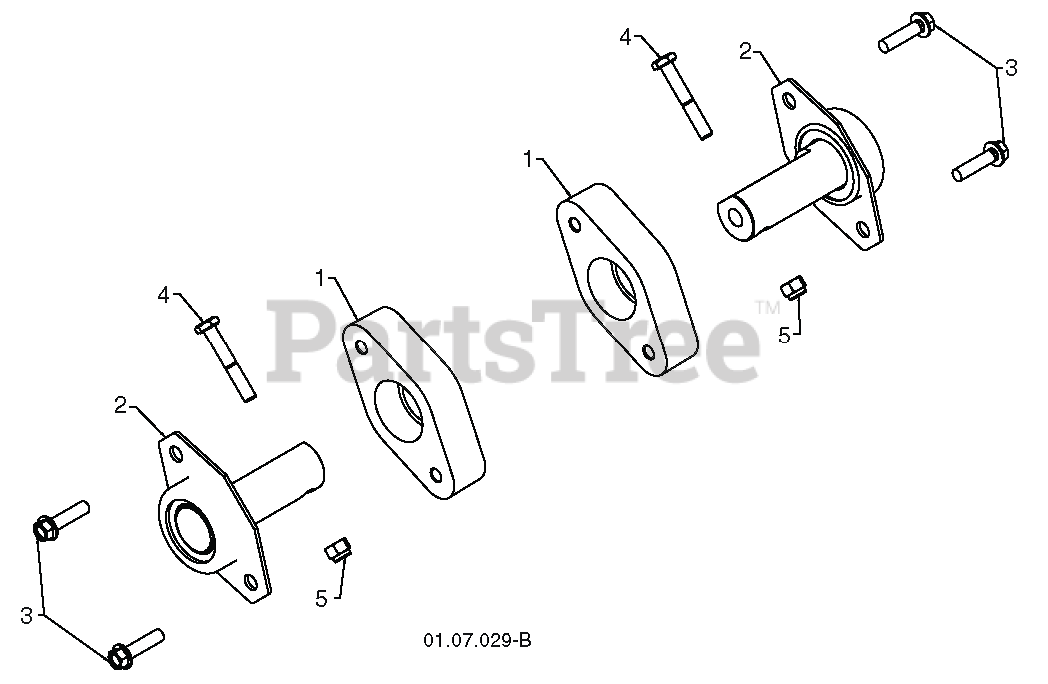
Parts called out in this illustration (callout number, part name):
1	DECAL.AUGER.SAFETY.
3	DECAL.CHUTE.SAFETY.
4	DECAL.AUGER."
6	DECAL.BELT.GUARD.
7	DECAL.NOISE.LEVEL.105DB/CE.EAC
